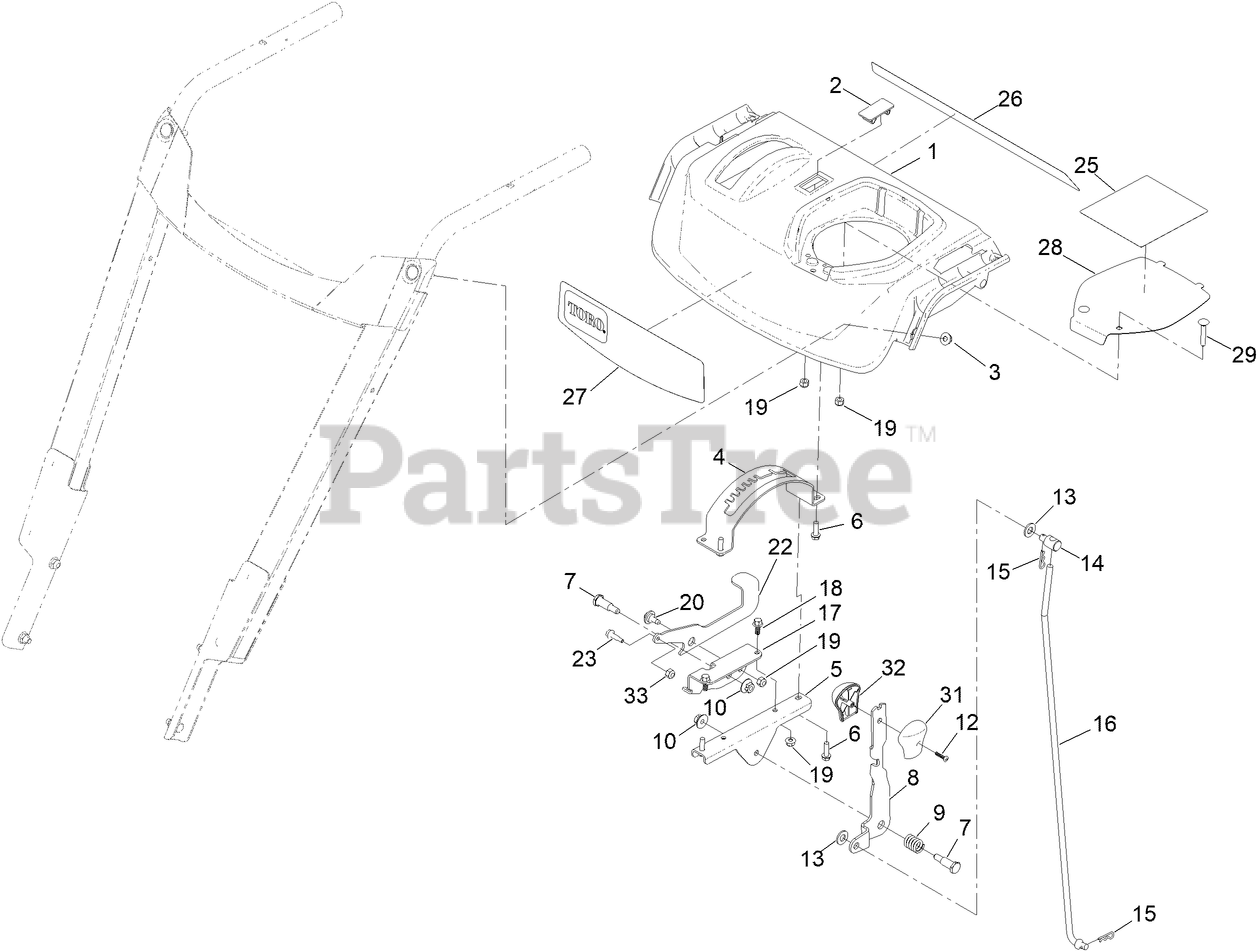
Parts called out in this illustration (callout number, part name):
1	PANEL-CONTROL
2	PLUG-HOLE
3	NUT-HF
4	GATE-SHIFT
5	BRACKET-SHIFT
6	SCREW-PLASTITE, HWH
7	SCREW-SHOULDER, HH
8	SELECTOR-SPEED
9	SPRING-COMPRESSION
10	NUT-HF
12	SCREW-PPH
13	WASHER-FLAT
14	TRUNNION-ROD
15	PIN-HAIR
16	ROD-SHIFT
17	BRACKET-LEVER, BROOM ANGLE
18	SCREW-HHF
19	NUT-FLANGE, NI
20	SCREW-SHOULDER
22	LEVER-BROOM ANGLE
23	SCREW-SHOULDER
25	DECAL-WARNING
26	DECAL-CONTROL PANEL
27	DECAL-CONSOLE
28	PLATE-COVER, CONT PNL
29	BOLT-CARR
31	KNOB-SHIFT, LH
32	KNOB-SHIFT, RH
33	NUT-HF
